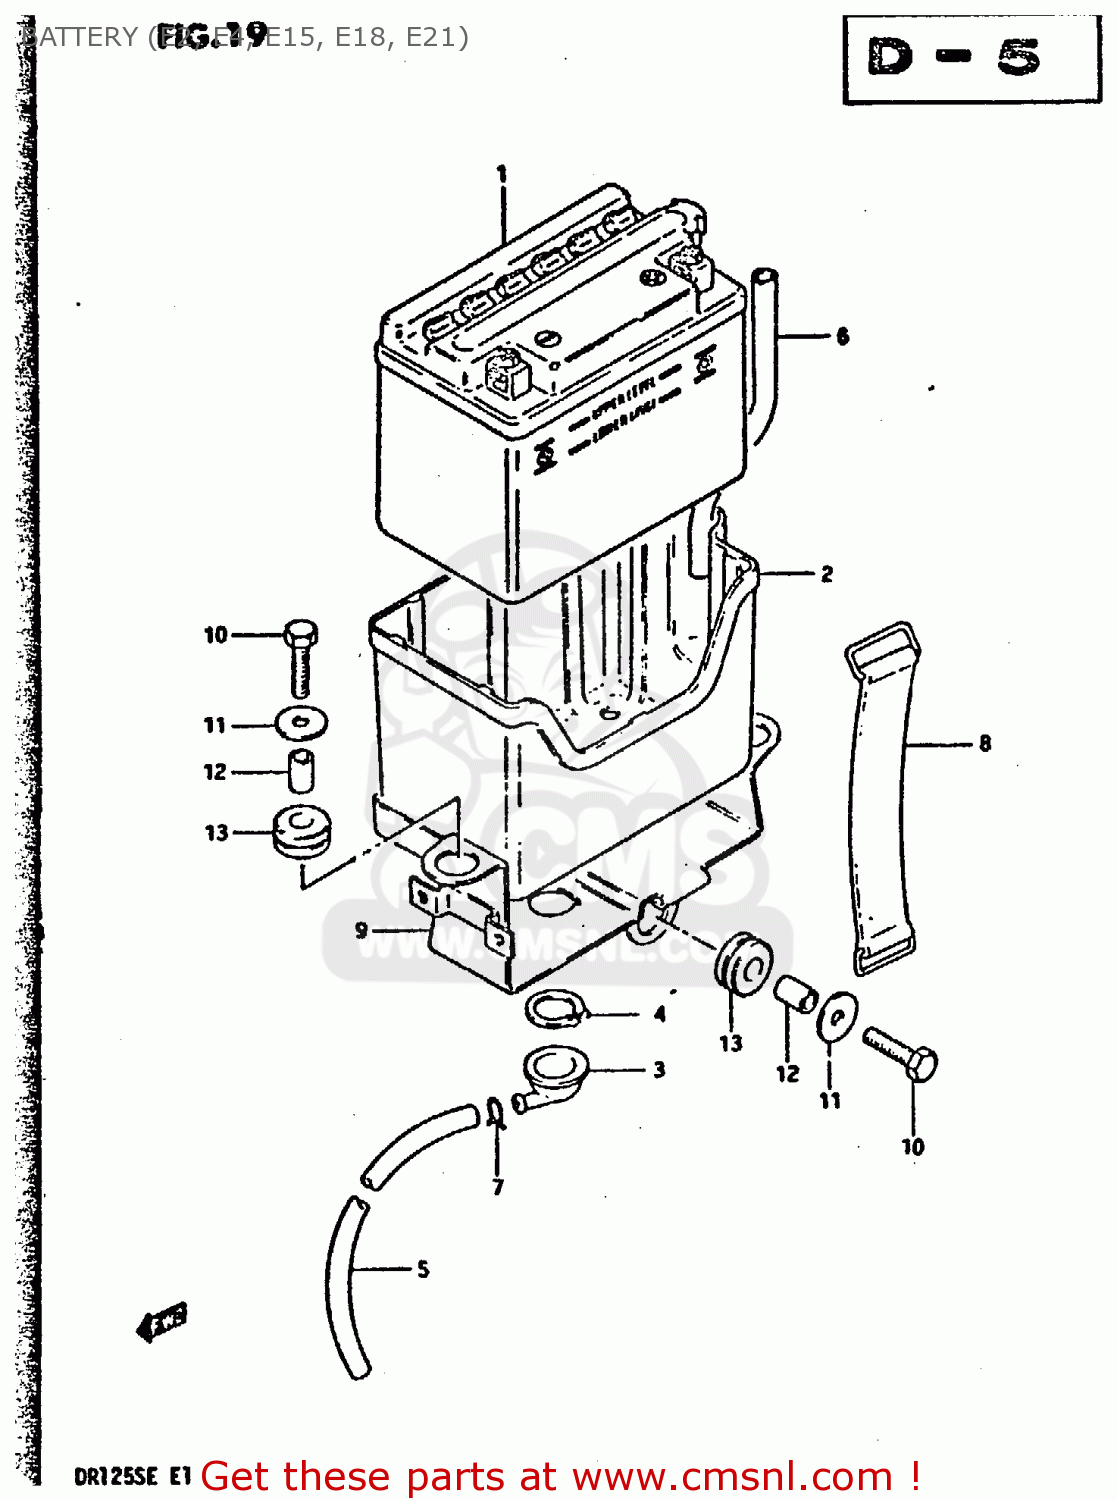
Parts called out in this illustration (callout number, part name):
1	BATTERY ASSY(YB4L-B,12V4.2AH)
2	CASE, BATTERY
3	FUNNEL,BATTERY EXHAUST
4	CIRCLIP
5	HOSE,BATTERY EXHAUST
6	HOSE, EXHAUST (L:45)
7	CLIP
8	BAND
9	HOLDER, BATTERY
10	BOLT, UPPER
11	WASHER (6.5X20X1.2)
12	SPACER(6.1X9X7.5)
13	CUSHION
